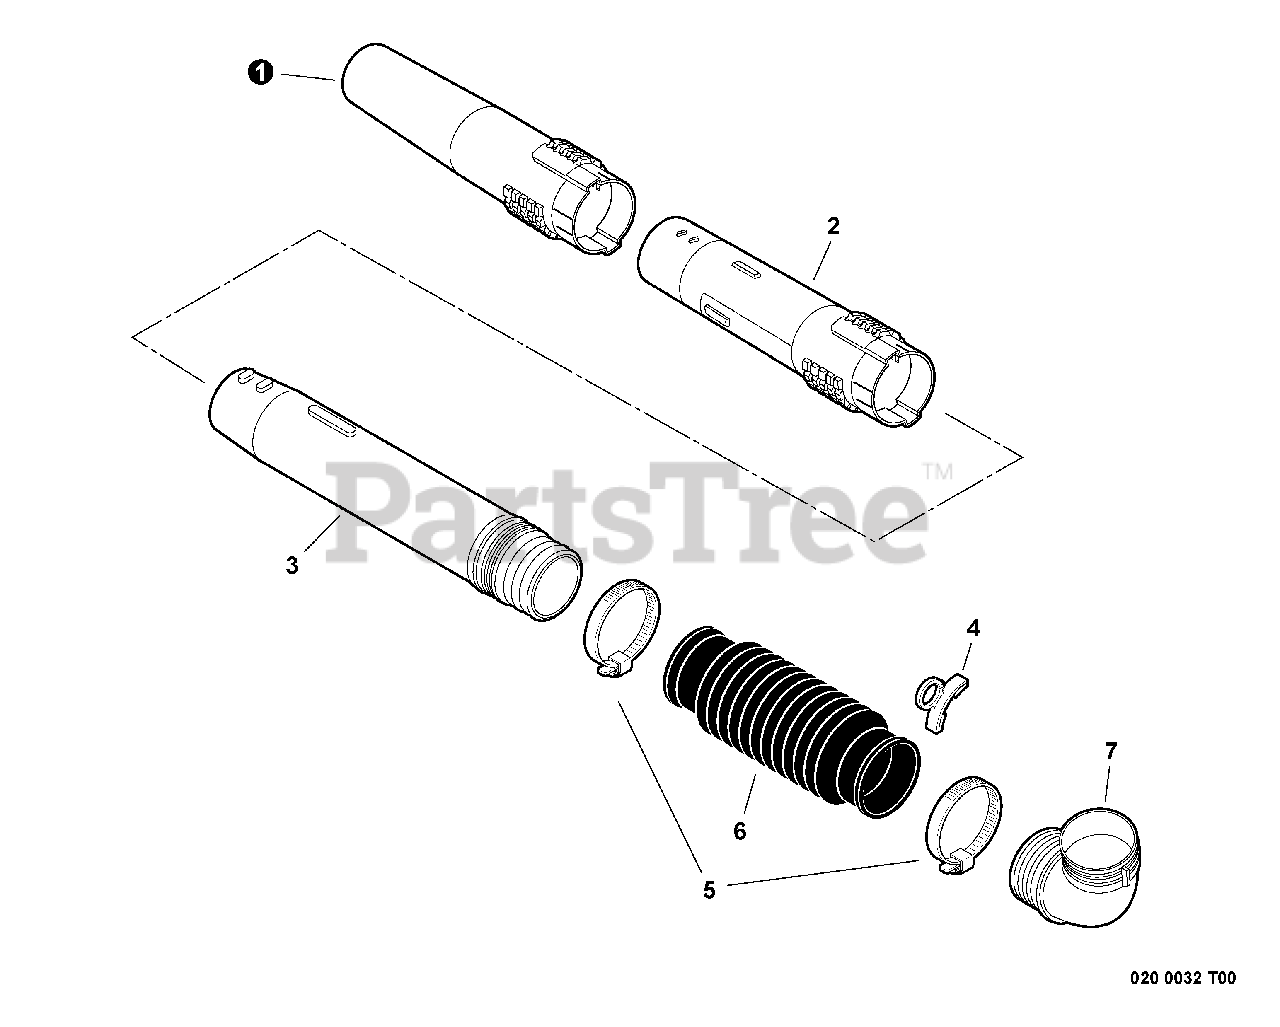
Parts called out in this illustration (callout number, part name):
1	TUBE, BLOWER - STRAIGHT NOZZLE
2	TUBE, BLOWER - STRAIGHT
3	TUBE, BLOWER - SWIVEL
4	CLIP, CABLE
5	CLAMP, HOSE
6	TUBE, BLOWER - FLEXIBLE
7	TUBE, BLOWER - ELBOW
